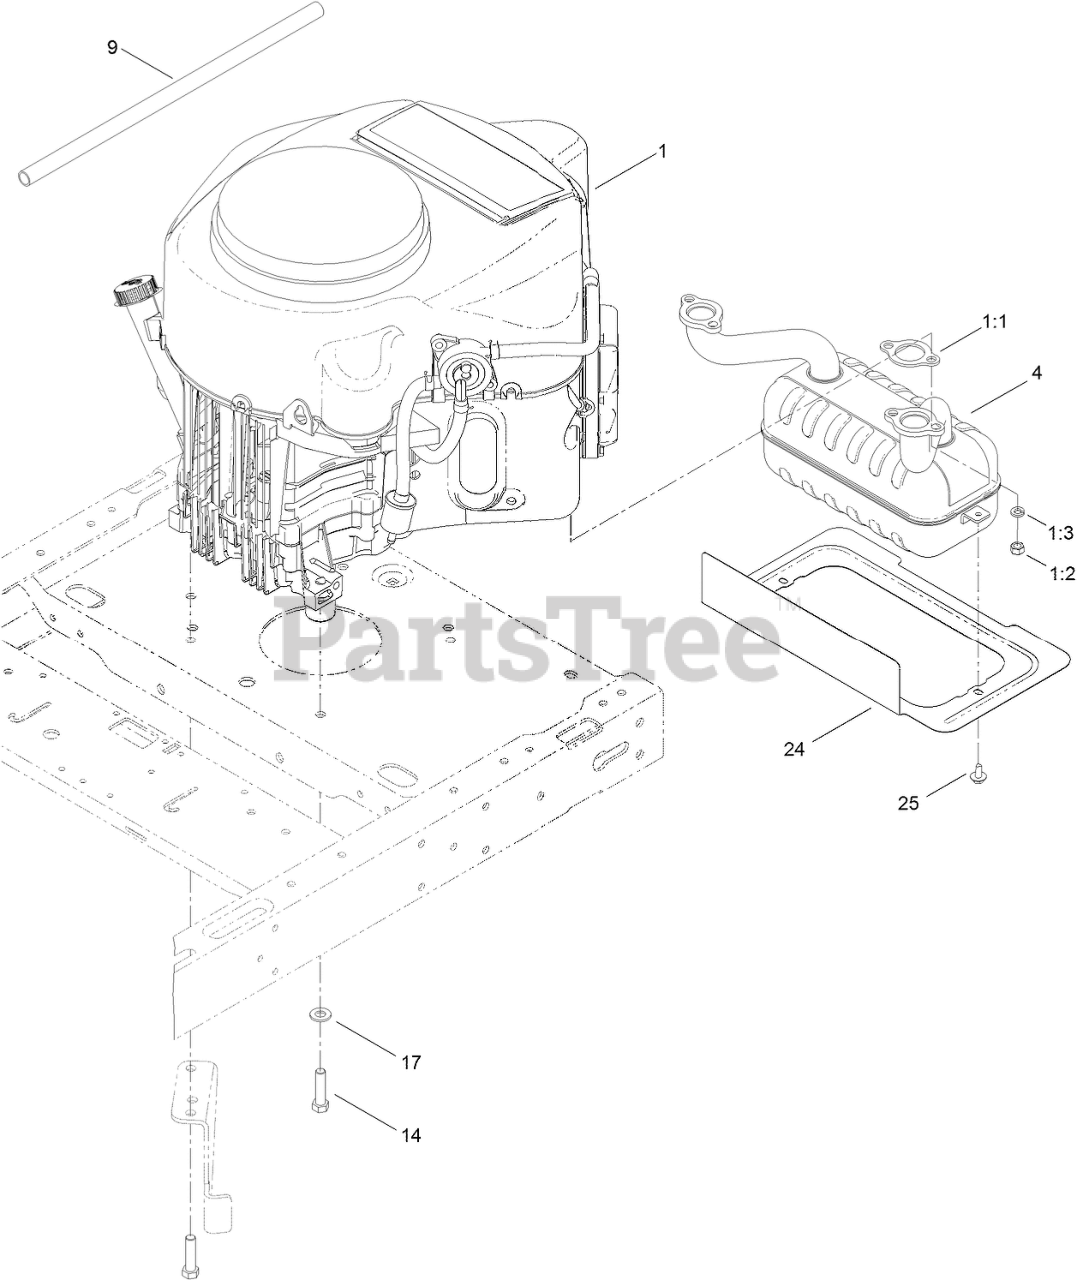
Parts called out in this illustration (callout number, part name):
1:1	GASKET-EXHAUST
1:3	WASHER-LOCK
4	MUFFLER-KAWASAKI
9	TUBE-DRAIN, OIL
14	BOLT-HH
17	WASHER-FLAT
24	SHIELD-HEAT
25	SCREW-HHFTF
